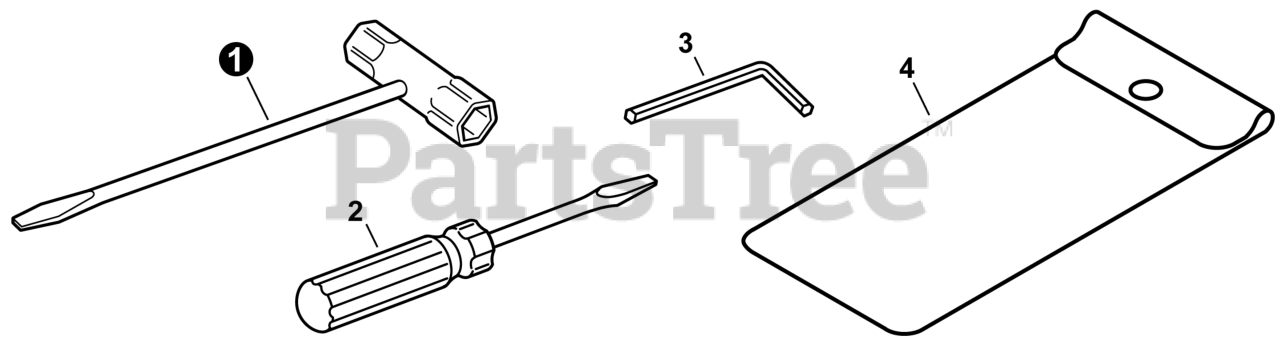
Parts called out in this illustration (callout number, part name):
1	T-WRENCH 13×19 L= 180
2	SCREWDRIVER, PHILLIPS
3	WRENCH, ALLEN 4 MM
4	BAG, TOOL
